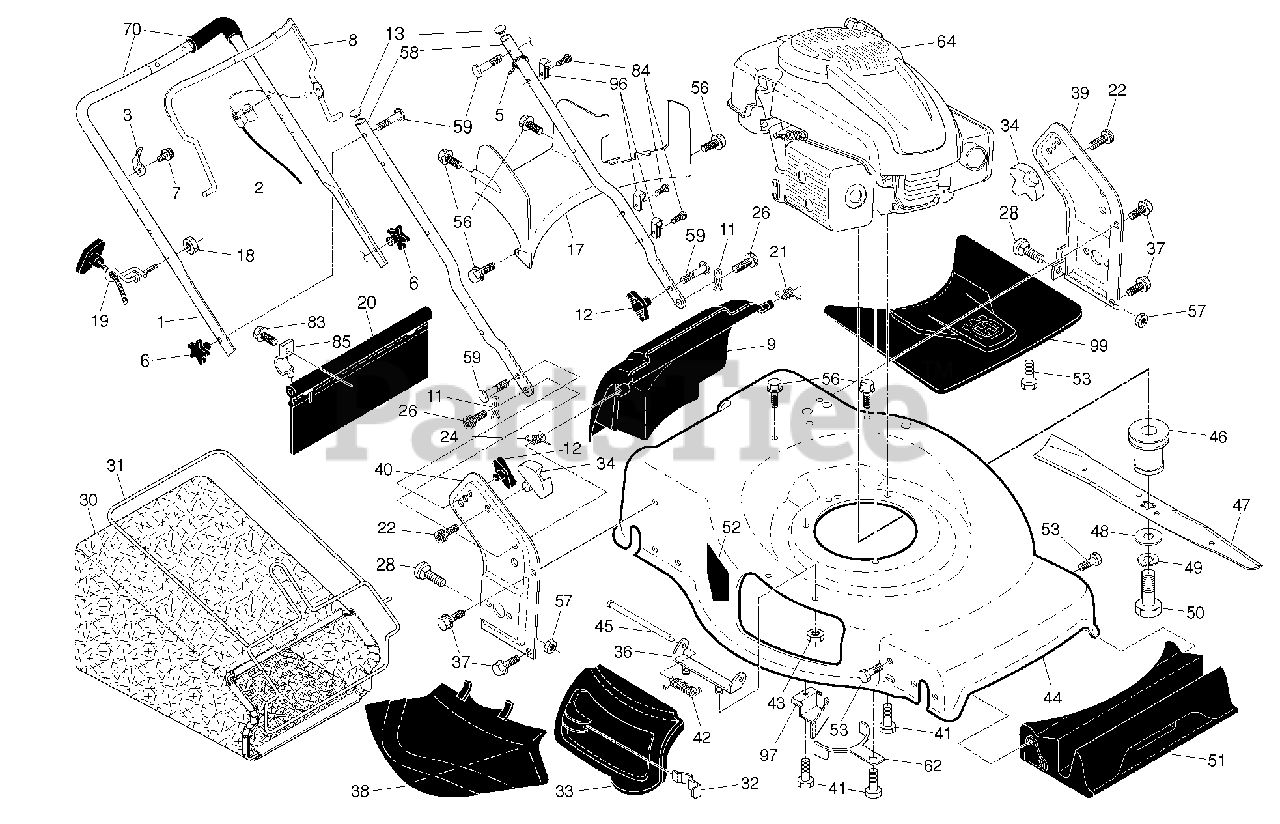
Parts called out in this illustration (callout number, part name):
1	HANDLE.ASM.UPPER.W/GRIP
2	CABLE.MZR.50.SNAP-IN
3	BRACKET.UPSTOP.RT
6	KNOB.HANDLE.PLASTIC.STAR.BLACK
8	BAIL.CONTROL.MZR.BS.ORANGE
9	DOOR.REAR.ASM.22+.HUSQ.FG/RGD
11	COTTER.HAIRPIN.DOOR/HANDLE.PIV
12	KNOB, DEFLECTOR
13	PLUG.PLASTIC.7/8".14-20.GAUGE
17	RP.BAFFLE.REAR.22+.RGD.PL
18	NUT
19	RB GUIDE.ROPE.STD.BLK.ZIN WSL
20	SKIRT.REAR.22+RGD.HIGH WHEEL
21	SPRING.LH.BLACK
22	SCREW.PAN.HEAD.#10
24	SPRING.RH.GRAY
26	SCREW,DOOR/HANDLE.PIVOT
28	BOLT
30	GBAG.B5610247T.SIL.HUSQ.BLUE
31	RB FRAME.GBAG.22PLUS
32	LATCH.DOOR.ZINC
33	DOOR.MULCH.22 PLUS.HUSQ.GREY
34	BRACKET.GRASSBAG.ATTACHING.BLK
36	BRACKET.ASM.HINGE.21.FWGD.
37	BOLT.5/16HEX.WHS.HD
38	DEFLECTOR.CLIPPING.22.BLACK
39	BRACKET.HANDLE.LT.22+.W/DP.GRE
40	RP.BRACKET.ASM.HANDLE.RT.22+.
41	BOLT 3/8-16X1-1/8
42	SPRING.TORSION
43	NUT.HEX.FLANGE.1/4
44	HOUSING.22+.RWD.WO/PORT.ORANGE
45	ROD.HINGE.21
46	ADPTER.BLAD.25M.VS.22PLU.STAR
47	BLADE.22+.4.N.1
48	WASHER,HARDEN
49	LOCKWASHER
50	SCREW, HEX HD 3/8-24 X 1-3/8
51	BAFFLE.FRONT.22PLUS.PLASTIC RP
52	DANGER DECAL
53	SCREW.HI-LO.5/16 X.75
56	SCREW.HX.13X.750
57	NUT.FLANGE.5/16
58	HANDLE.LOWER.22+BT.2PC.GRY
59	BOLT, HANDLE 5/16-18X1.75
62	BRACKET.ENG/BELTKEEPER
70	GRIP.HANDLE.FOAM.WIDE.(1 SIDE)
83	TAPPING SCREW
84	FASTENER.PUSH.O.250X0.783
85	BRACKET.SKIRT.22+.BZP
96	CLIP.CABLE.BLK
97	BRACKE.BELT.GUIDE.22+
99	COVER.ASM.FRONT.SHROUD.HUSQ.
